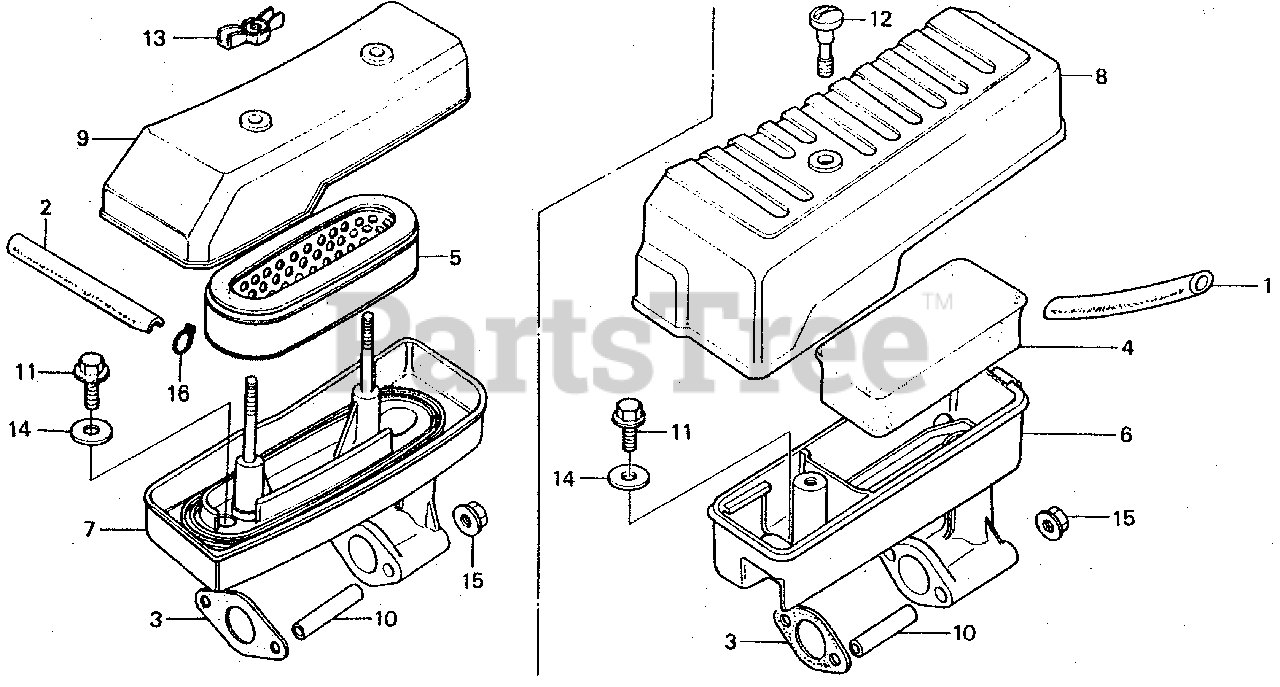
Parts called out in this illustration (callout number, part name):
1	TUBE, BREATHER
2	TUBE, BREATHER (NOT AVAILABLE)
3	GASKET, AIR CLEANER
4	ELEMENT, AIR CLEANER
5	ELEMENT, AIR CLEANER
6	HOUSING, AIR CLEANER
6	HOUSING, AIR CLEANER (NOT AVAILABLE)
7	HOUSING, AIR CLEANER
8	COVER, AIR CLEANER *NH1* (BLACK) (NOT AVAILABLE)
9	COVER, AIR CLEANER *NH1* (BLACK)
10	COLLAR, AIR CLEANER HOUSING
11	BOLT, FLANGE (6X12) (CT200)
12	BOLT, AIR CLEANER COVER (NOT AVAILABLE)
13	WINGNUT, AIR CLEANER COVER
14	WASHER, HEADLIGHT CASE
15	NUT, FLANGE (6MM)
16	CLIP, TUBE (B12.5)
